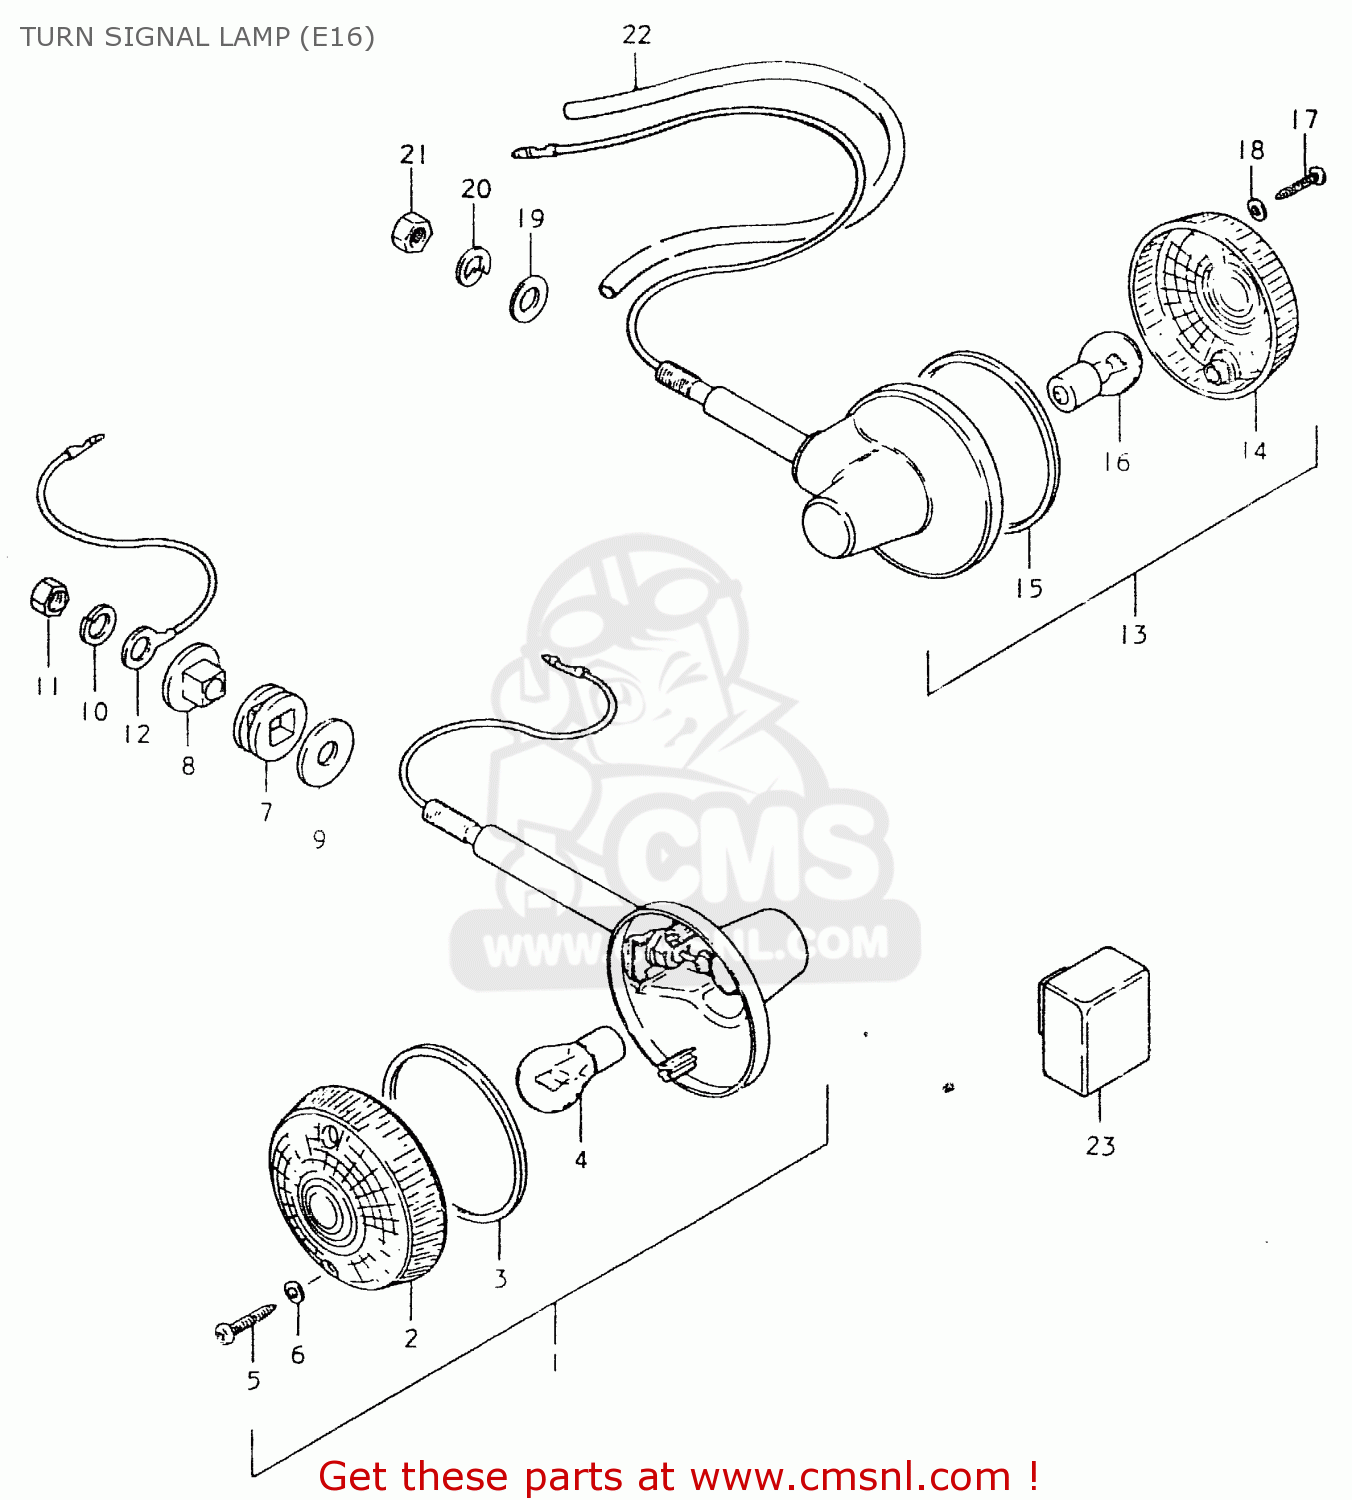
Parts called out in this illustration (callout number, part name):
1	LAMP ASSY, FRONT TURN SIGNAL
2	LENS
3	GASKET (NAS)
4	BULB (6V,21W)
5	SCREW
6	GASKET (NAS)
7	CUSHION
8	SPACER,TURN SIGNAL LAMP
9	WASHER (10.5X30X2.3)
10	LOCK WASHER
11	NUT
12	LEAD WIRE,EARTH
13	LAMP ASSY, REAR TURN SIGNAL
14	LENS
15	GASKET (NAS)
16	BULB (6V,21W)
17	SCREW
18	GASKET (NAS)
19	WASHER
20	LOCK WASHER
21	NUT
22	PROTECTOR, LEAD WIRE
23	RELAY, TURN SIGNAL
